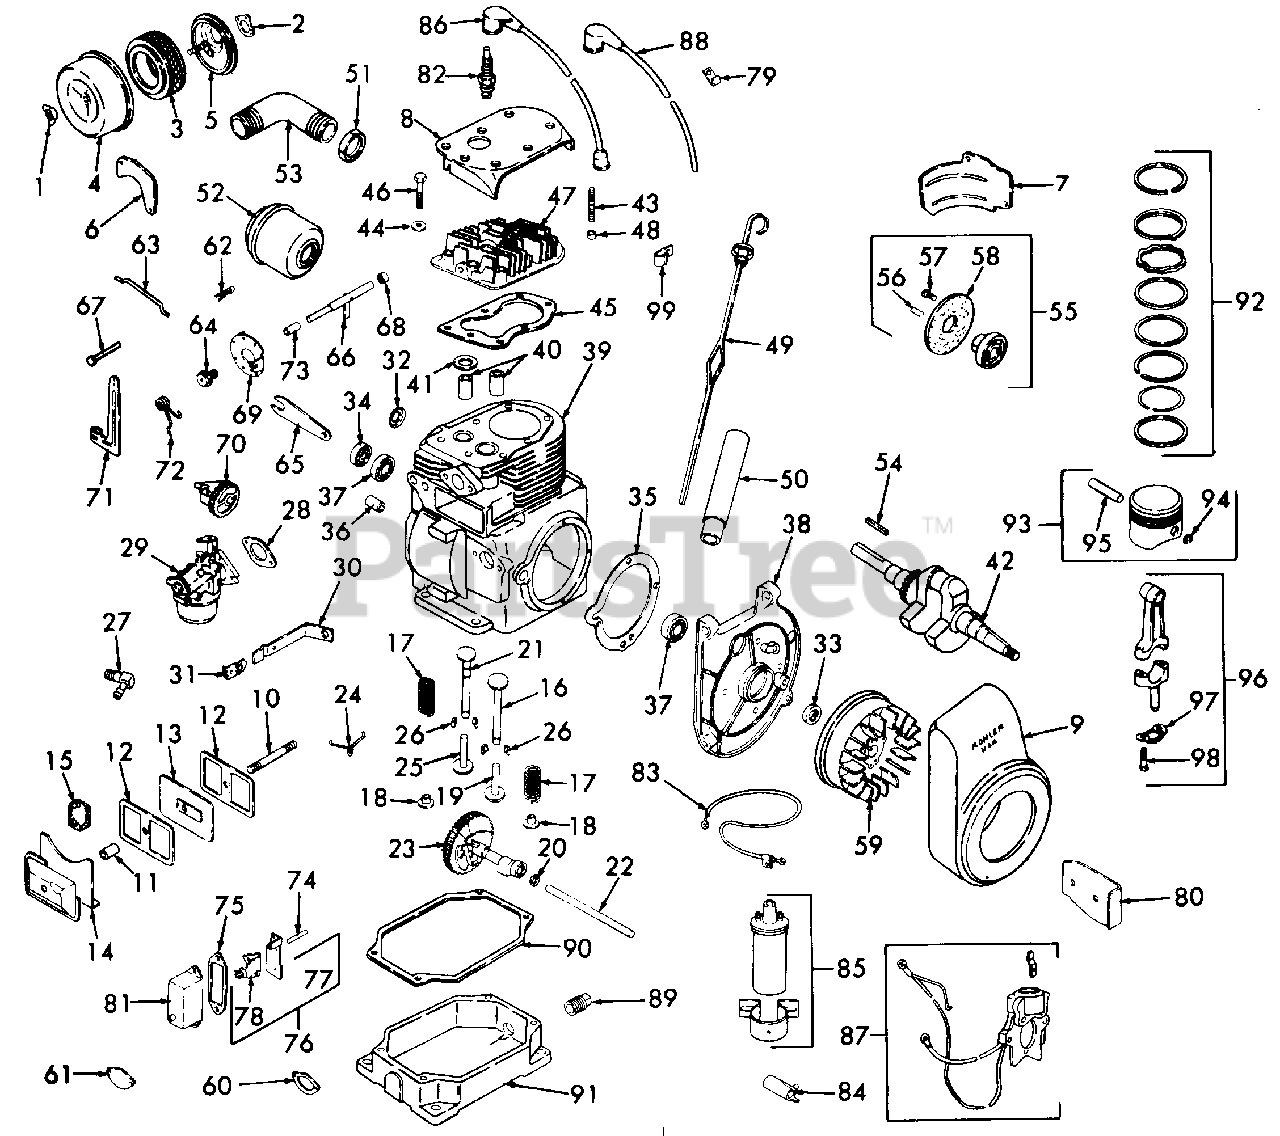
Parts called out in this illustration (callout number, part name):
1	Nut 1/4-20 Wing
3	Element, Air Cleaner
4	Cover, Air Cleaner
5	Base, Air Cleaner
6	Baffle, Side Air
7	Baffle, Cylinder
8	Baffle, Head
9	Housing, Blower
10	Stud, Valve Cover
11	Seal, Breather
12	Gasket, Valve Cover
13	Breather Assy
14	Cover Assy, Valve
15	Filter
16	Valve, Intake
17	Spring, Valve
18	Retainer, Spring
19	Tappet, Intake Valve
20	Spacer, Camshaft, .005
20	Spacer, Camshaft, .010
21	Valve, Exhaust
22	Pin, Camshaft
23	Camshaft Assy
24	Spring, Actuating
25	Tappet, Exhaust Valve
26	Keeper, Spring
28	Gasket, Carburetor
29	Carburetor Assy
30	Bracket, Choke
32	Plug, Expansion
33	Seal, Front Oil
34	Seal, Rear Oil
36	Shaft, Governor
37	Bearing, Ball
38	Plate, Bearing
39	Mini Block Assy
40	Guide, Valve
41	Insert, Exhaust Valve
42	Crankshaft
43	Stud
45	Gasket, Head
46	Screw, 5/16-18 X 1-1/2 Hex Cap
47	Head, Cylinder
49	Dipstick Assy
50	Tube, Oil Fill
51	Nut, Lock
52	Muffler
53	Elbow, Exhaust
54	Key
55	Cup Assy, Flywheel Drive
56	Pin, 1/4 X 3/4
58	Screen
59	Flywheel
60	Gasket, Fuel Pump Pad
61	Cover, Fuel Pump Pad
62	Pin
63	Linkage, Governor
64	Bushing, Governor
65	Bracket, Speed Control
66	Shaft, Governor
67	Pin, Governor Stop
68	Bearing, Needle
69	Disc, Regulating
70	Gear, Governor
71	Lever, Governor
72	Spring, Governor
73	Spacer
74	Rod, Breaker
75	Gasket, Cover
76	Breaker Assy
77	Bracket, Breaker Point
80	Bracket, Coil
81	Cover, Breaker
82	Plug, Spark
83	Lead, Breaker
84	Condenser
85	Coil, Ignition
86	Cable, High Tension
87	Stator Assy
88	Lead, Hi-Tension
89	Plug, 3/8 Pipe
92	Ring Set, Piston, Std
93	Piston Assy, Std
94	Retainer, Pin
95	Pin, Piston, Std
96	Rod Assy, Connecting, Std
97	Lock, Connecting Rod
98	Screw, Connecting Rod
99	Clip, Choke Cable
